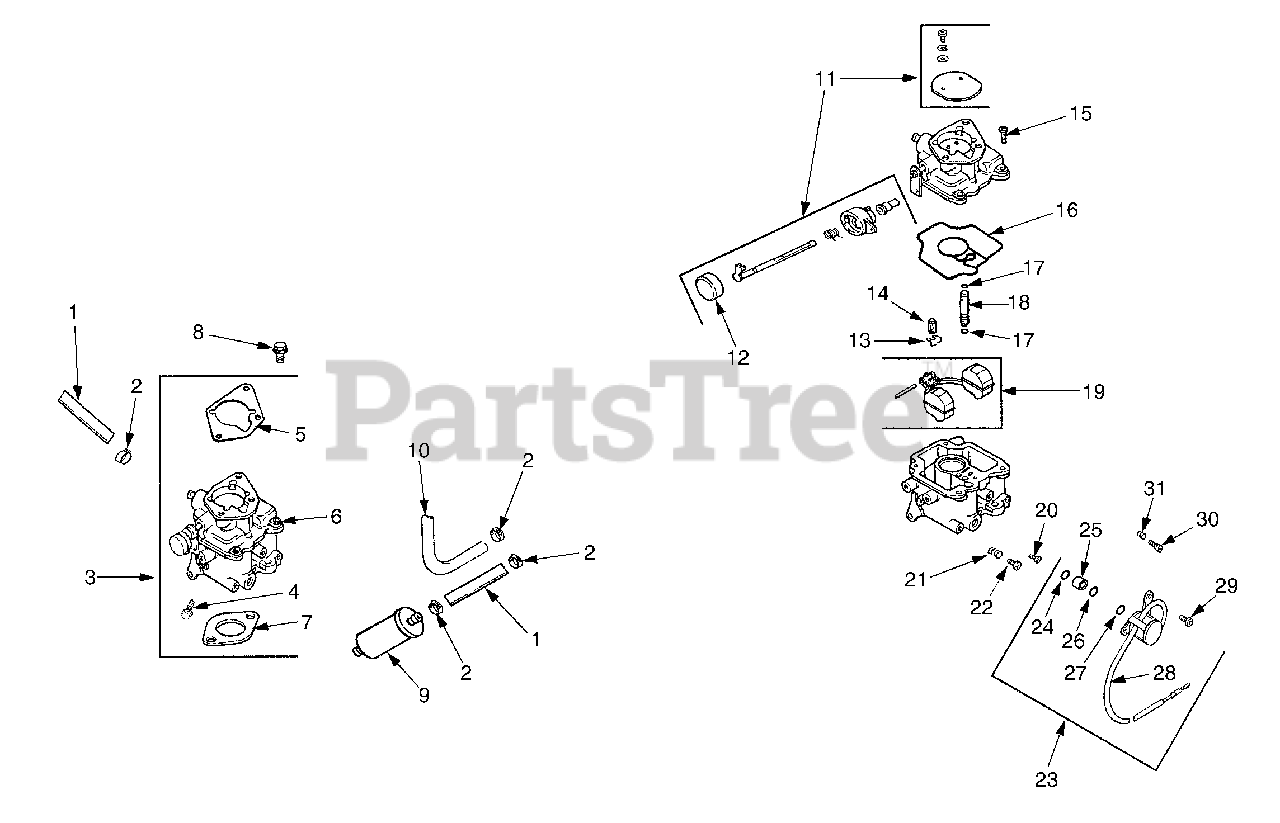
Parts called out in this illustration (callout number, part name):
1	Line, Fuel 10"
2	Clamp, Hose
3	Kit, Carburetor w/Gasket
4	Screw, Throttle Stop
5	Gasket, Air Cleaner Base
6	Carburetor Assembly
7	Gasket, Carburetor
8	Screw, Hex Flange
9	Filter, Fuel
10	Line, Fuel 11"
11	Kit, Choke Repair
12	Cap, Choke Lever
13	Clip, Inlet Needle Value
14	Valve, Inlet Needle
15	Screw, Carburetor Body
16	Gasket, Carburetor Body
17	O-Ring Slow Jet
19	Kit, Float Repair
21	Spring, Idle Adjust Screw
22	Screw, Idle Adjusting
23	Kit, Solenoid
25	Seat, Solenoid
28	Solenoid
29	Screw, Solenoid
30	Needle, Idle
31	Spring, Idle Needle
